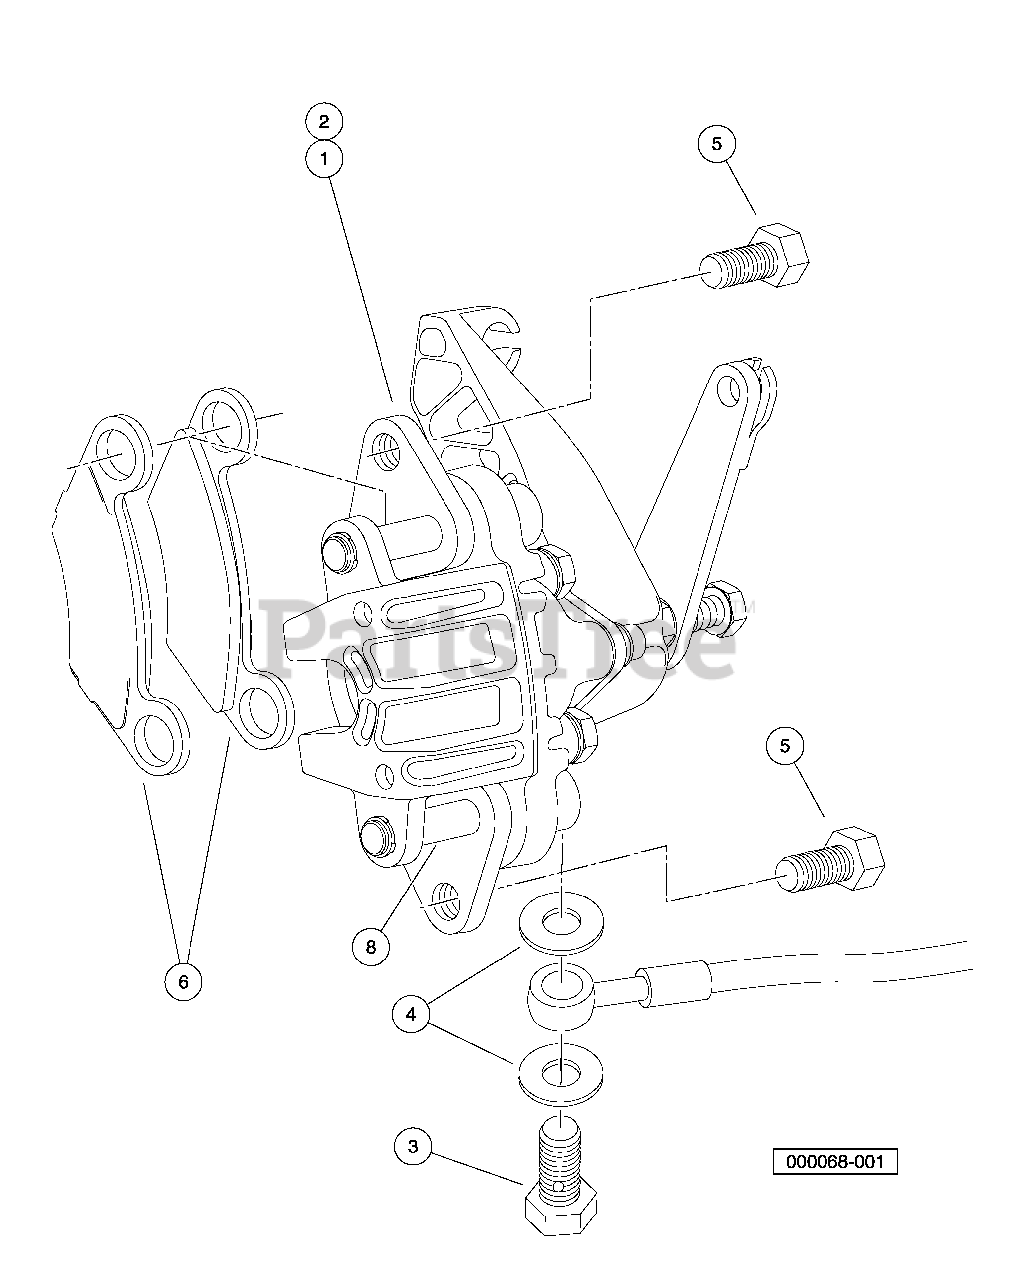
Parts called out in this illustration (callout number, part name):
1	Caliper, Brake, Hydro-Mechanical, LH
2	Caliper, Brake, Hydro-Mechanical, RH
3	Bolt, Banjo, M10x1x19
4	Washer, Copper, M10 Crush
5	Bolt Flange Head, 3/8-24x.750 with Loctite
6	Service Kit, Brake Pad
7	Spring, Brake Caliper Return
8	Pin, Slide, 7/16
